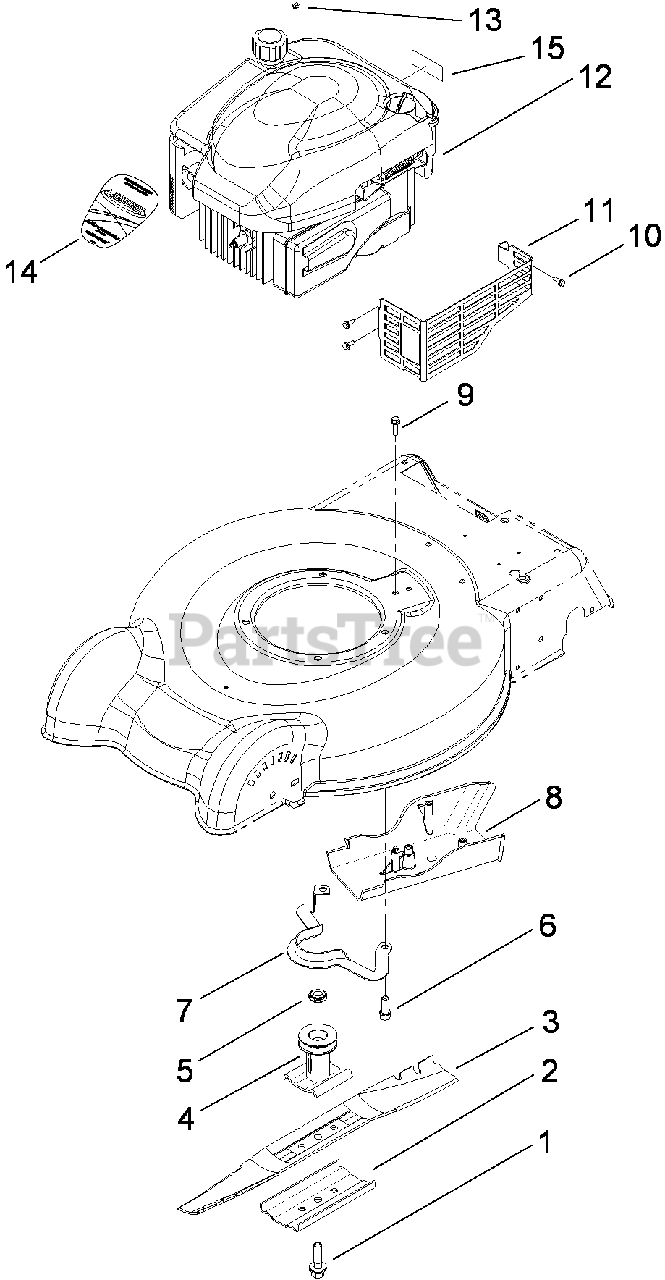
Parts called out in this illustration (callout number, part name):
1	BOLT-BLADE
2	SUPPORT-BLADE
3	BLADE-20 INCH
4	BLADE DRIVER ASM
5	Spacer-Driver
6	SCREW-TAPTITE
8	COVER-BELT
9	SCREW-HWH
10	SCREW-TAPTITE
11	SHIELD-MUFFLER
13	STOP-ROPE
15	DECAL-ARRESTER, SPARK
